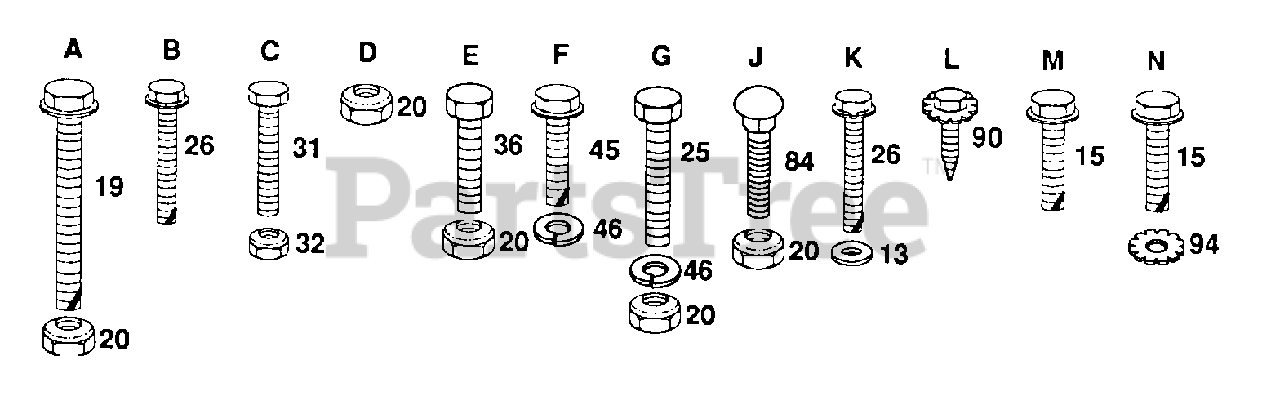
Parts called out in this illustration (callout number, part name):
13	WASHER
15	SCREW
19	BOLT
25	BOLT
26	SCREW
31	BOLT
45	SCREW
46	WASHER
84	BOLT
94	LOCKWASHER
